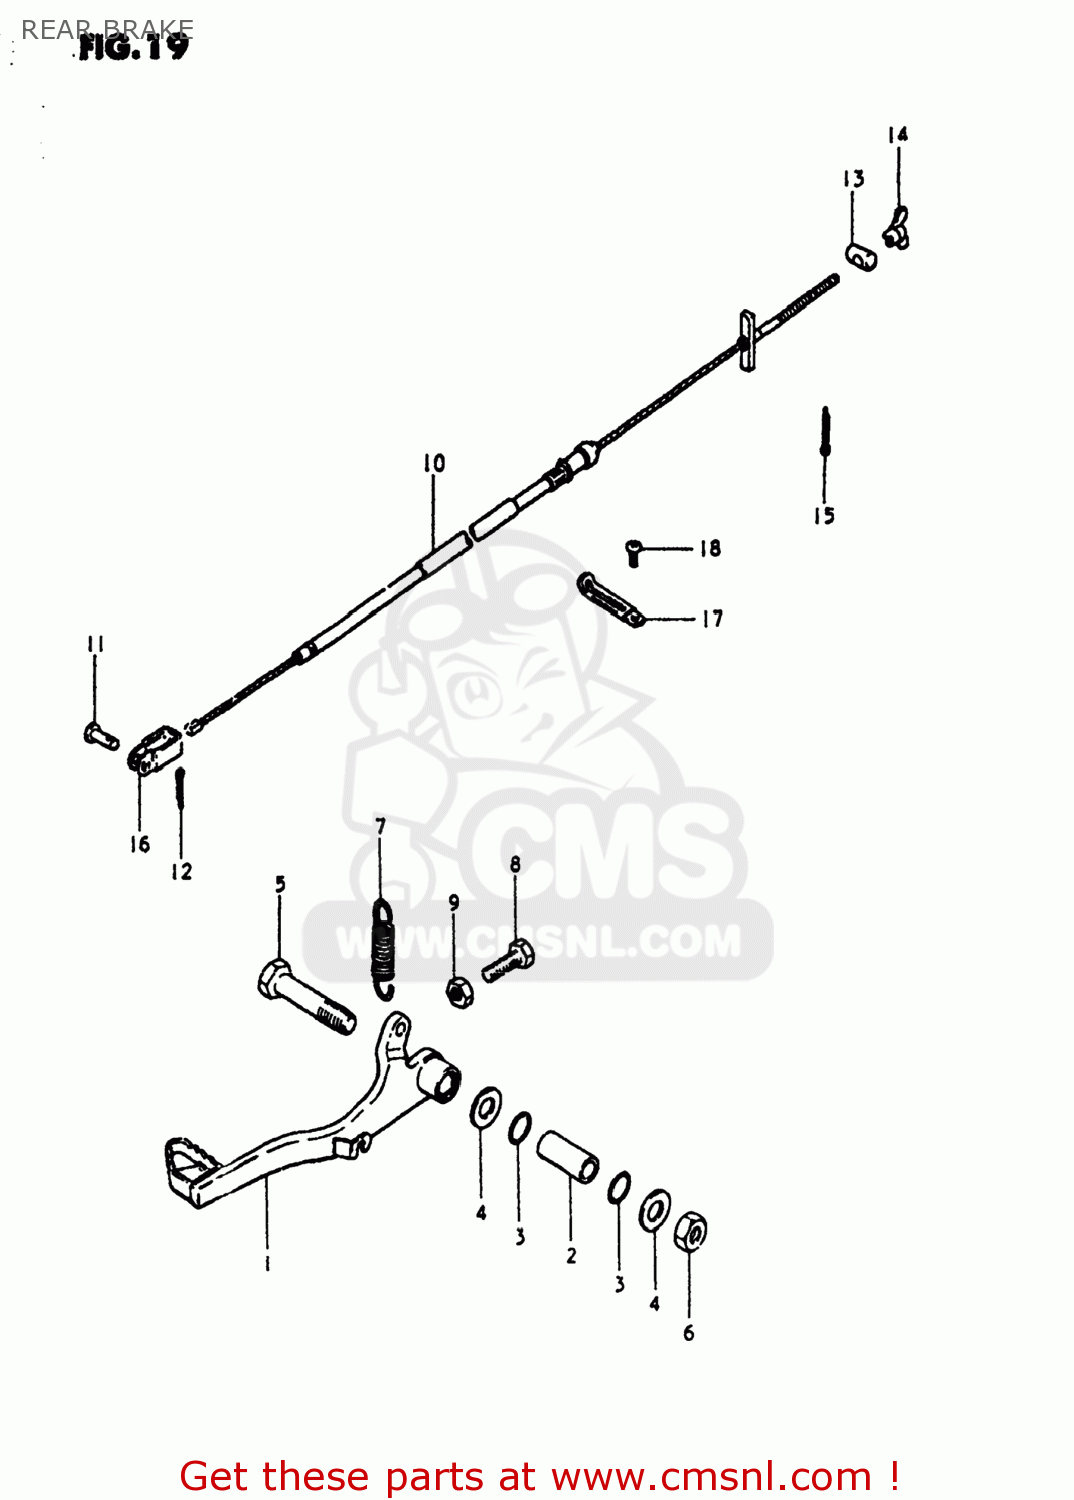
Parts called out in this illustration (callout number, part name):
1	PEDAL,BRAKE
2	SPACER (8X10X22)
3	O-RING (D:1.5 ID:10)
4	WASHER
5	BOLT
6	NUT
7	SPRING
8	BOLT(6X23)
9	NUT
10	CABLE,RR BRAKE
11	PIN(L:13)
12	PIN
13	PIN
14	NUT
15	PIN
16	HOOK,REAR BRAKE PEDAL
17	CLAMP
18	SCREW,6X6
